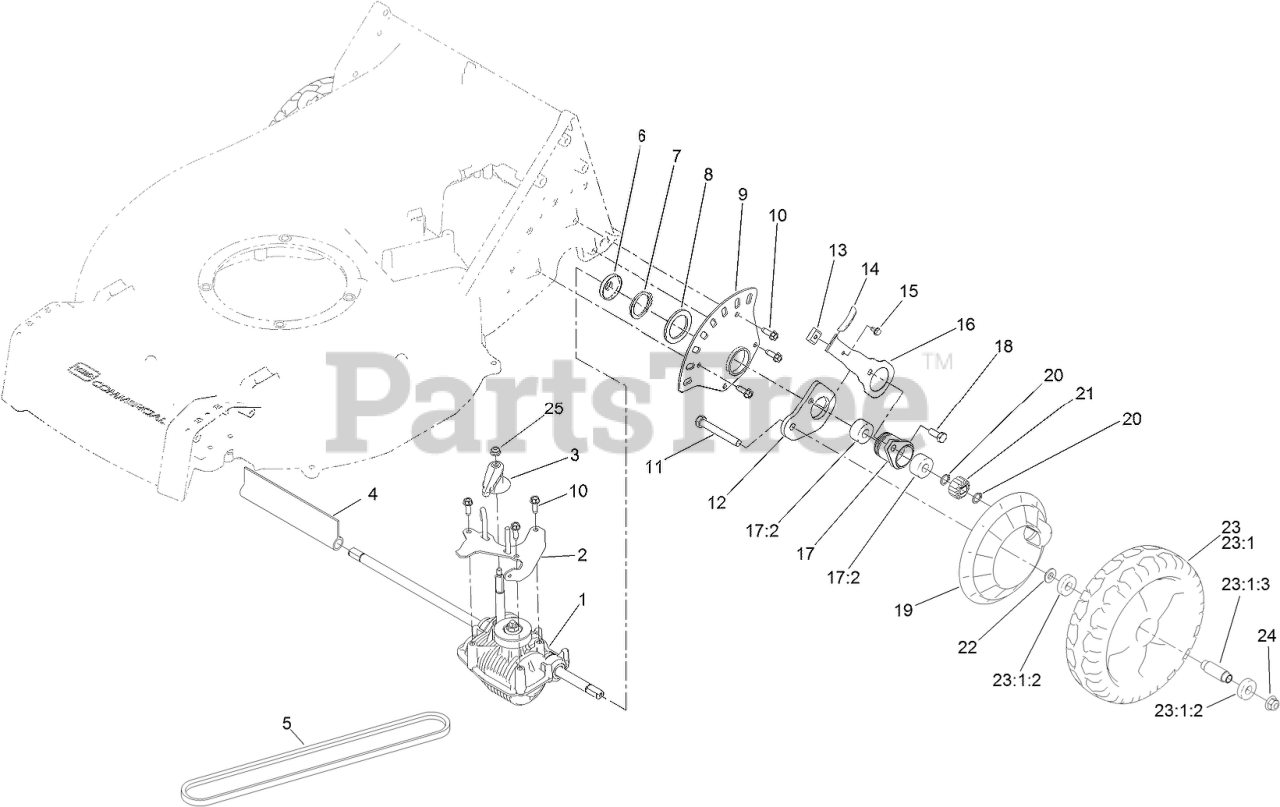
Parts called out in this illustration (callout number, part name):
1	TRANSMISSION
2	GUIDE-BELT
3	LEVER-SHIFT
4	COVER-SHAFT, TRANSMISSION
5	BELT-V
6	COVER-BEARING
7	RING-RETAINING
8	WASHER-THRUST
9	PLATE-HOC, REAR
10	SCREW-HWHTF
11	SCREW-HH
12	ARM-PIVOT, REAR
13	KEY-ARM, SPRING
14	KNOB-LEVER, HOC
15	SCREW-HWH
16	ARM-SPRING, REAR
17	BEARING RETAINER ASM
17:2	BEARING-BALL, CUSTOM
18	SCREW-HH
19	COVER-WHEEL
20	RING-RETAINING
21	GEAR-PINION, 15T
22	SPACER-COVER, WHEEL
23	9-INCH WHEEL ASM
23:1	WHEEL
23:1:2	BEARING-BALL
23:1:3	SPACER
24	NUT-HF, NI
25	NUT-HF
